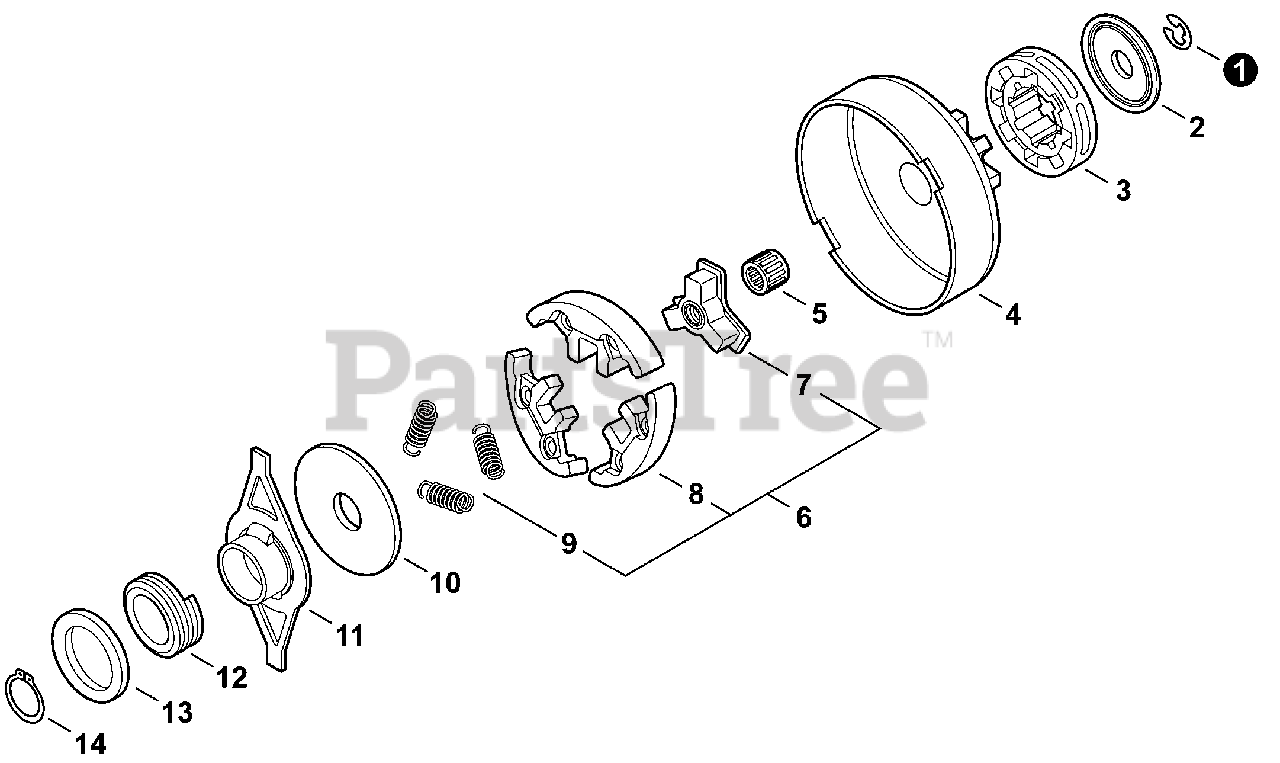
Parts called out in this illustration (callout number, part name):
1	E-RING Ø8.1
2	WASHER 10
3	SPROCKET, RIM 3/8"×7T
4	DRUM, CLUTCH
5	BEARING, NEEDLE 10
6	CLUTCH ASSY
7	HUB, CLUTCH
8	SHOE SET, CLUTCH (3PCS)
9	SPRING, TENSION
10	PLATE, CLUTCH
11	COLLAR 15×19×73
12	GEAR, WORM
13	WASHER 15.5×22.5×0.5
14	RING, RETAINING 15
